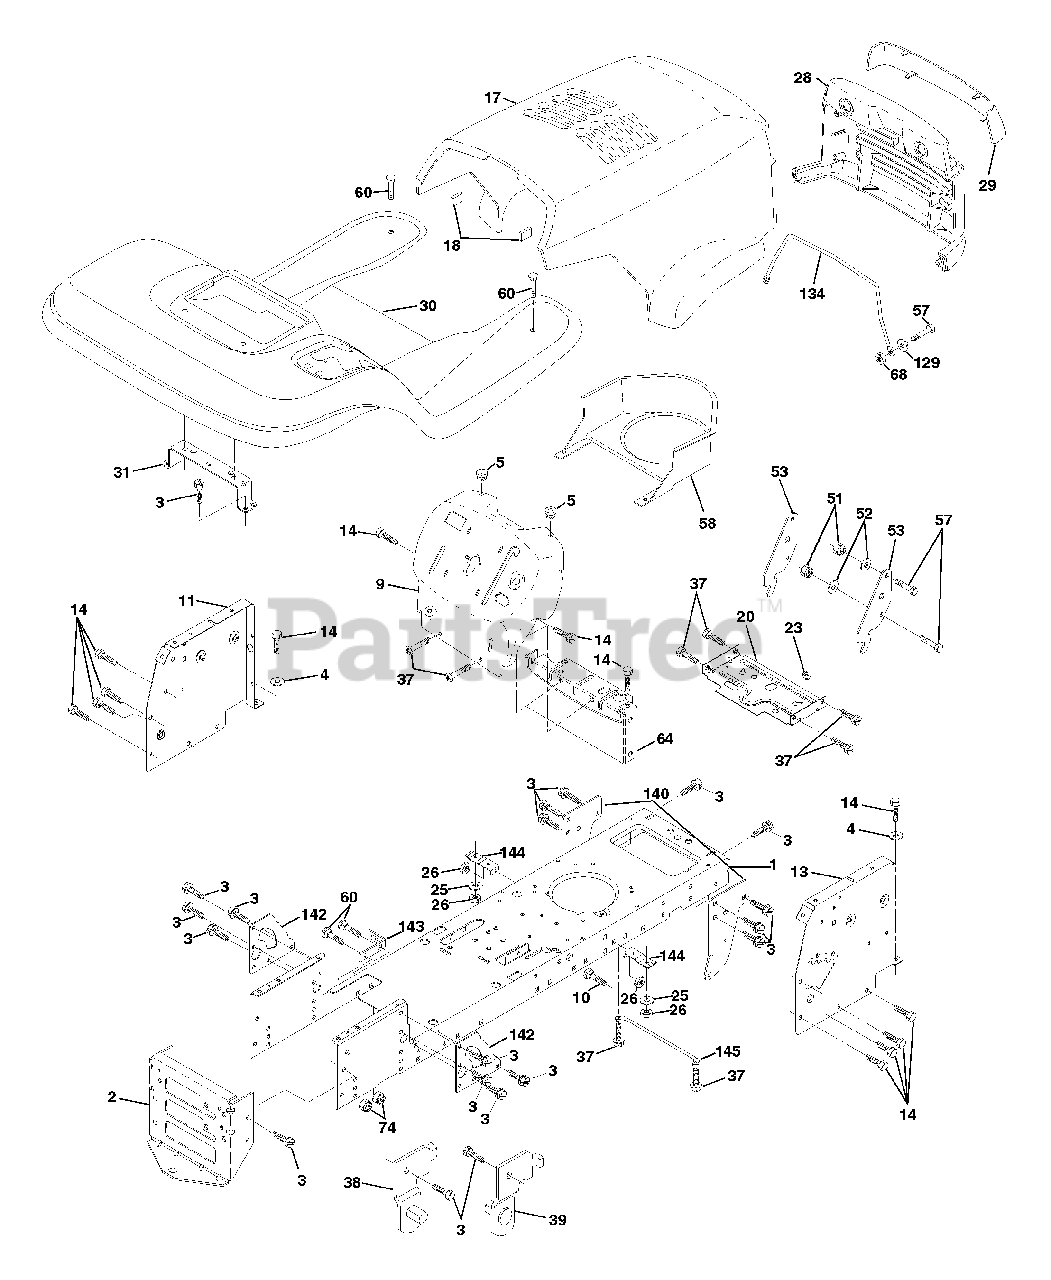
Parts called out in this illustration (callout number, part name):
1	Chassis Weldment
2	Drawbar, Stretch
3	Screw Thdrol 3/8-16 x 3/4 Ty-tt
4	Washer 13/32 x 3/4 x 16 Ga.
5	Bumper Hood/Dash
9	Dash P/L M, N/AMM N/HM
10	Bolt Carriage 3/8-16 x 1
11	Panel Dash Lh
13	Panel Dash Rh
14	Screw Thdrol 3/8-16 x 1/2 Ty-tt
17	Hood LT/PL Husqvarna
18	Bumper Hood
20	Plate Mtg Battery Fuel Tank Fr
25	Washer 13/32 X 13/16 X 12 Ga
26	Nut Lock Hex W/Ins 3/8-16 Unc
28	Grille LT/PL Husqvarna
29	Lens LT/PL Husqvarna
30	Fender Footrest STLT Pnt
31	Bracket Support Fender
37	Screw Thdrol 6/16-18 x 1/2 TYT
38	Bracket, Asm. Pivot, L.H., Mower Rear
39	Bracket, Asm. Pivot, R.H., Mower Rear
51	Nut Lock Hex W/Ins 1/4-20
52	Washer 9/32 x 7/8 x 16 Ga.
53	Bracket Pnt. Pick off LT/PL Husqvarna
57	Bolt Hex 1/4-20 x 3/4
58	Air Duct Engine P/L
60	Bolt Rdhd Sqnk 3/8-16unc x 3/4
64	Dash Lower STLT
68	Nut Keps Hex 1/4-20 unc
74	Nut Crownlock 3/8-16 UNC
129	Washer 9/32 x 5/8 x 16 Ga.
134	Rod Support Hood LT/PL Husq.
140	Bracket Suspension Front
142	Plate Reinforcement STLT
143	Bracket Swaybar Chassis
144	Bracket Pnt Footrest STLT
145	Rod Pivot Chassis/Hood
